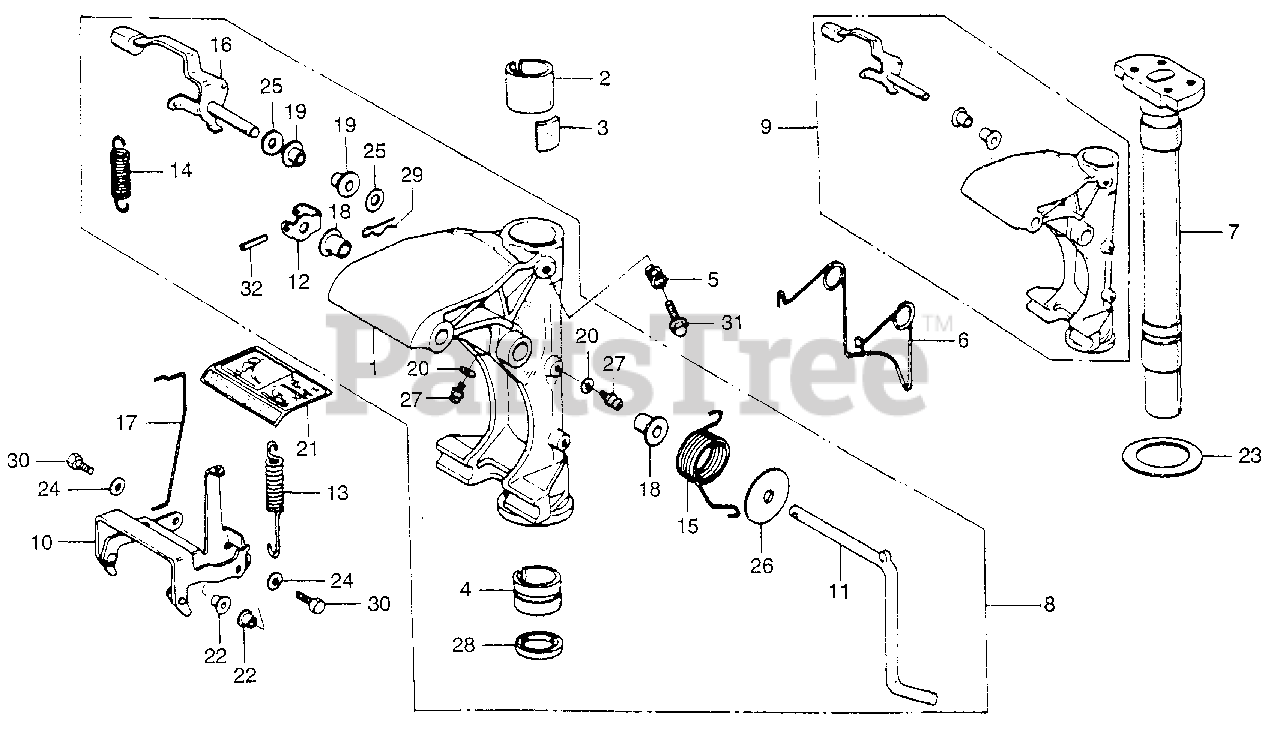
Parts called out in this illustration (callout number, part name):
1	CASE, SWIVEL *B9* (ATLANTIS BLUE)
2	LINER, SWIVEL CASE
3	BLOCK, FRICTION
4	BUSH, SWIVEL SHAFT
5	SPRING, FRICTION ADJUSTING
6	SPRING, HOOK RETURN
7	SHAFT, SWIVEL *B9* (ATLANTIS BLUE) (NOT AVAILABLE)
8	CASE, SWIVEL *B9* (ATLANTIS BLUE)
8	CASE, SWIVEL *B107* (SENIOR BLUE)
9	CASE, SWIVEL *B9* (ATLANTIS BLUE)
10	LOCK, REVERSE
11	LINK, TILT (NOT AVAILABLE)
12	BRACKET, TILT LEVER
13	SPRING, REVERSE LOCK
14	SPRING, TILT LEVER
15	SPRING, TILT LINK
16	LEVER, TILT
16	LEVER, TILT (NOT AVAILABLE)
17	ROD, RELEASE SWIVEL CASE
19	BUSH B, TILT LEVER
20	WASHER (6X11)
21	PLATE, SETTING CAUTION
22	COLLAR (6MM)
23	WASHER, THRUST
24	WASHER, PLAIN (6MM)
25	WASHER, PLAIN (10MM)
26	WASHER, PLAIN (10MM)
27	FITTING, GREASE
28	OIL SEAL (32X37X7)
29	PIN, LOCK (10MM)
30	BOLT, HEX. (6X16)
31	BOLT, HEX. (8X20) (NOT AVAILABLE)
32	PIN, SPRING (4X25)
